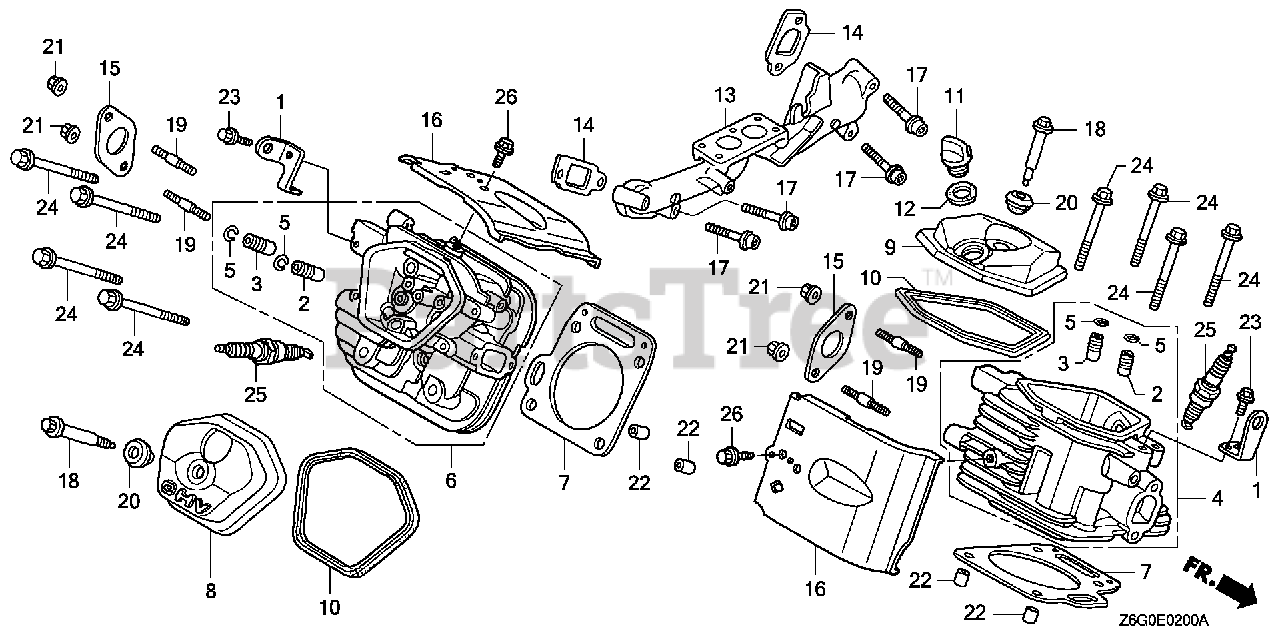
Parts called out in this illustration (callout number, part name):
1	HANGER, ENGINE
2	GUIDE, VALVE (OS)
3	GUIDE, EX. VALVE (OS)
4	CYLINDER HEAD (#1)
5	CLIP, VALVE GUIDE
6	CYLINDER HEAD (#2)
7	GASKET, CYLINDER HEAD
8	COVER, HEAD
9	COVER, HEAD FILLER
10	GASKET, CYLINDER HEAD COVER
11	CAP, OIL FILLER
12	GASKET, OIL FILLER CAP
13	MANIFOLD, IN.
14	GASKET, IN. MANIFOLD
15	GASKET, EX. PIPE Use up to Engine SN 2949254.
15	GASKET, EX. PIPE (WACKER)
16	SHROUD, HEAD
17	BOLT, SOCKET (8X45)
18	BOLT, HEAD COVER
19	BOLT, STUD (8X22)
20	WASHER, HEAD COVER
21	NUT, FLANGE (8MM)
22	PIN A, DOWEL (12X20)
23	BOLT, FLANGE (8X20) Use up to Engine SN 1609606.
24	BOLT, FLANGE (10X80)
25	SPARK PLUG (BPR2ES) (NGK)
25	SPARK PLUG (J14CR-U)
25	SPARK PLUG (ZGR4A) (NGK)
25	SPARK PLUG (J16CR-U)
25	SPARK PLUG (ZGR5A) (NGK)
26	BOLT, FLANGE (6X14)
